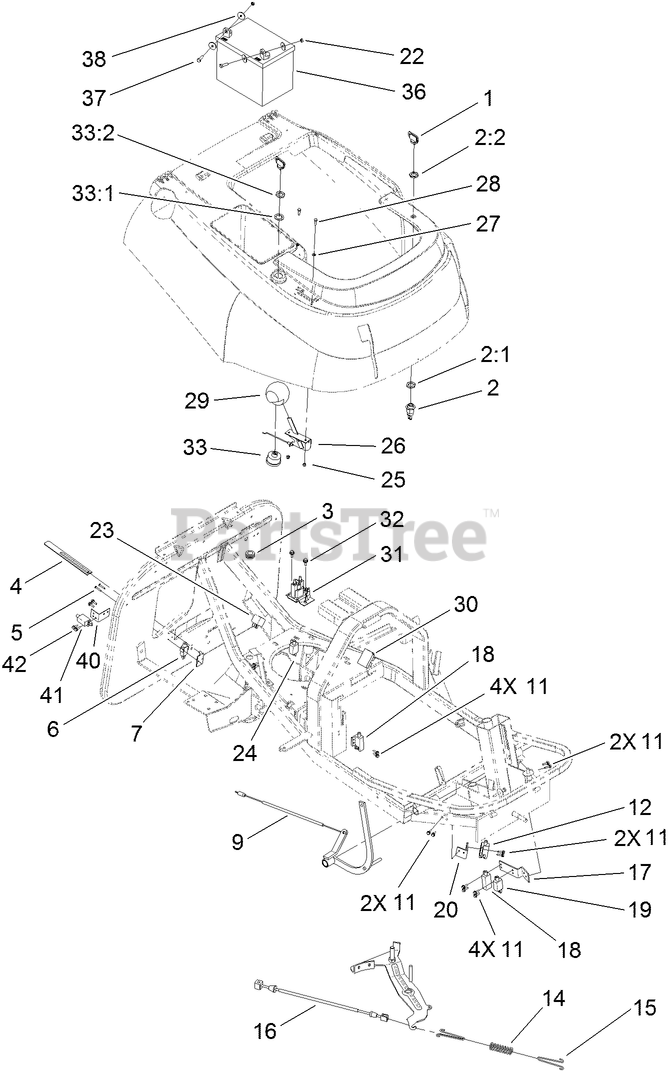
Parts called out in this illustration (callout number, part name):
1	KEY-IGNITION
2	STARTER SWITCH ASM
2:1	WASHER-LOCK
2:2	NUT-HH
3	Grommet
4	Lever-Bag Fill
6	Switch
7	Clamp-Bag Fill
9	CABLE-BRAKE
11	SCREW-HH, TAP
14	Spring-Compression
15	Hook-Spring
17	Bracket-Switch
20	Bracket-Switch
22	NUT-HEX
23	RELAY
25	NUT-LOCK
26	Throttle Cable ASM
27	WASHER
28	SCREW-HH
30	MODULE
32	SCREW-HHF, TAP
33:1	WASHER-LOCK
33:2	NUT-HH
37	SCREW-HH
38	Washer-Flat
40	BRACKET-COLLECTOR, SWITCH
42	SCREW-HH, TAP
